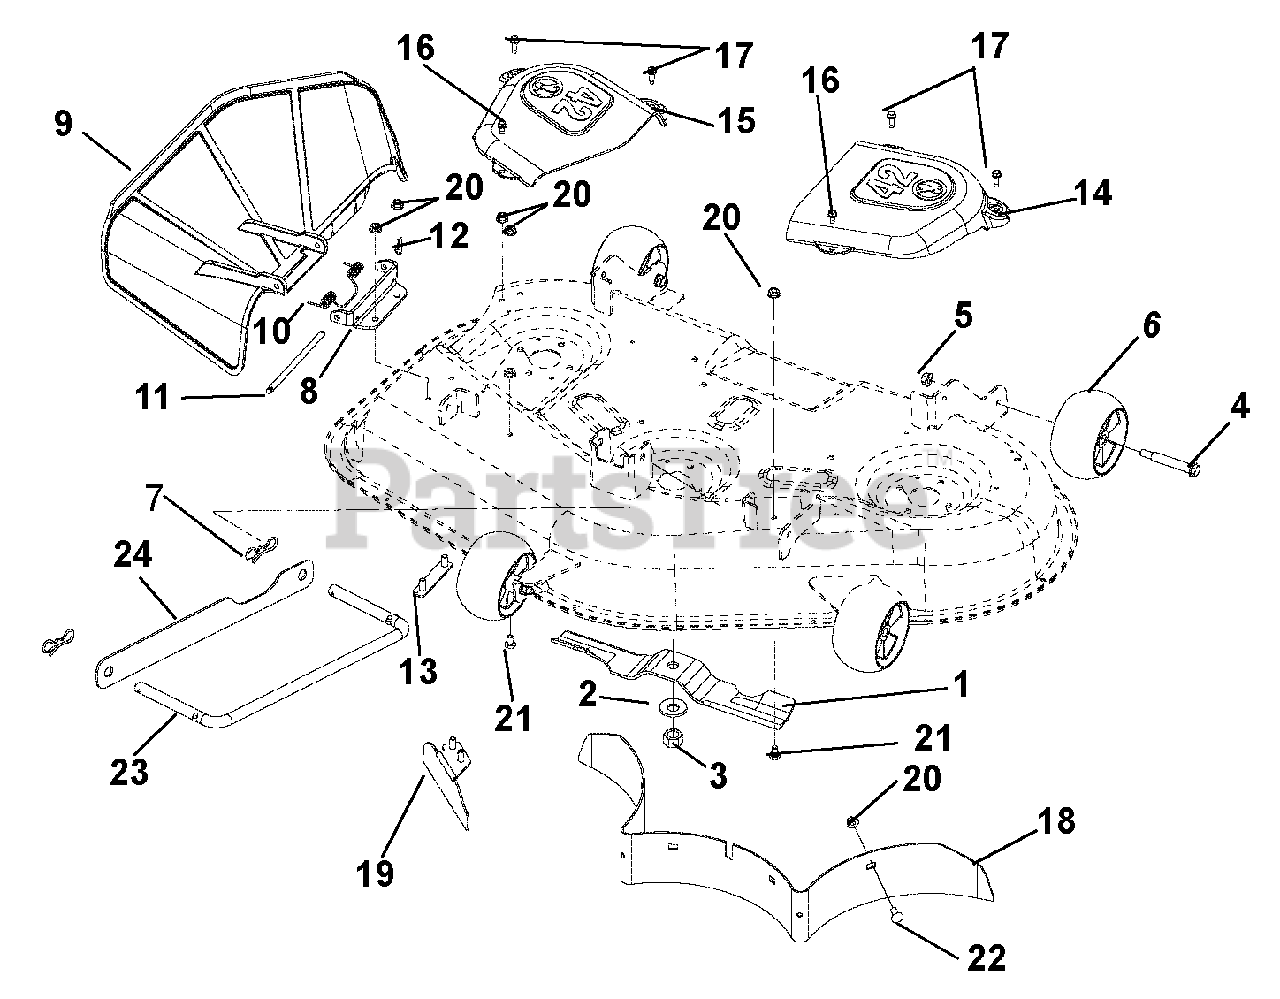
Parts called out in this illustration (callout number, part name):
1	Mower Blade, 14.83"
2	Washer, Bellville .63 x 1.625 x .14
3	Nut, Hex .62-18
4	Bolt, Shoulder .38-16 x 2.50 Hex Washer Head
5	Nut, Locking Top Flange .38-16
6	Anti-Scalp Wheel, 5 x 3 OS
7	Pin, Bow Tie Locking Cotter .091 x 1.875
8	Bracket, Discharge Chute Mount 42"
9	Discharge Chute – Molded
10	Spring, Torsion
11	Pin, 5/16 x 5.80"
12	Pin, Hair Internal .08 x .18 x 1.18
13	Weldment, Discharge Chute MT. Strap
14	Belt Cover, Left Hand 42"
15	Belt Cover, Right Hand 42"
16	Screw, Tapping .25-20 x .50 Hex Washer Head
17	Screw, Tapping .25-20 x .75 Hex Washer Head
18	Baffle, 42 Rear
19	Weldment – Baffle, Discharge 42"
20	Nut, Locking Top Flange .31-18
21	Bolt, Hex .31-18 x .50
22	Bolt, Round Head Square Neck .31-18 x .75
23	Wireform, Drag Link
24	Strap, Drag Link
